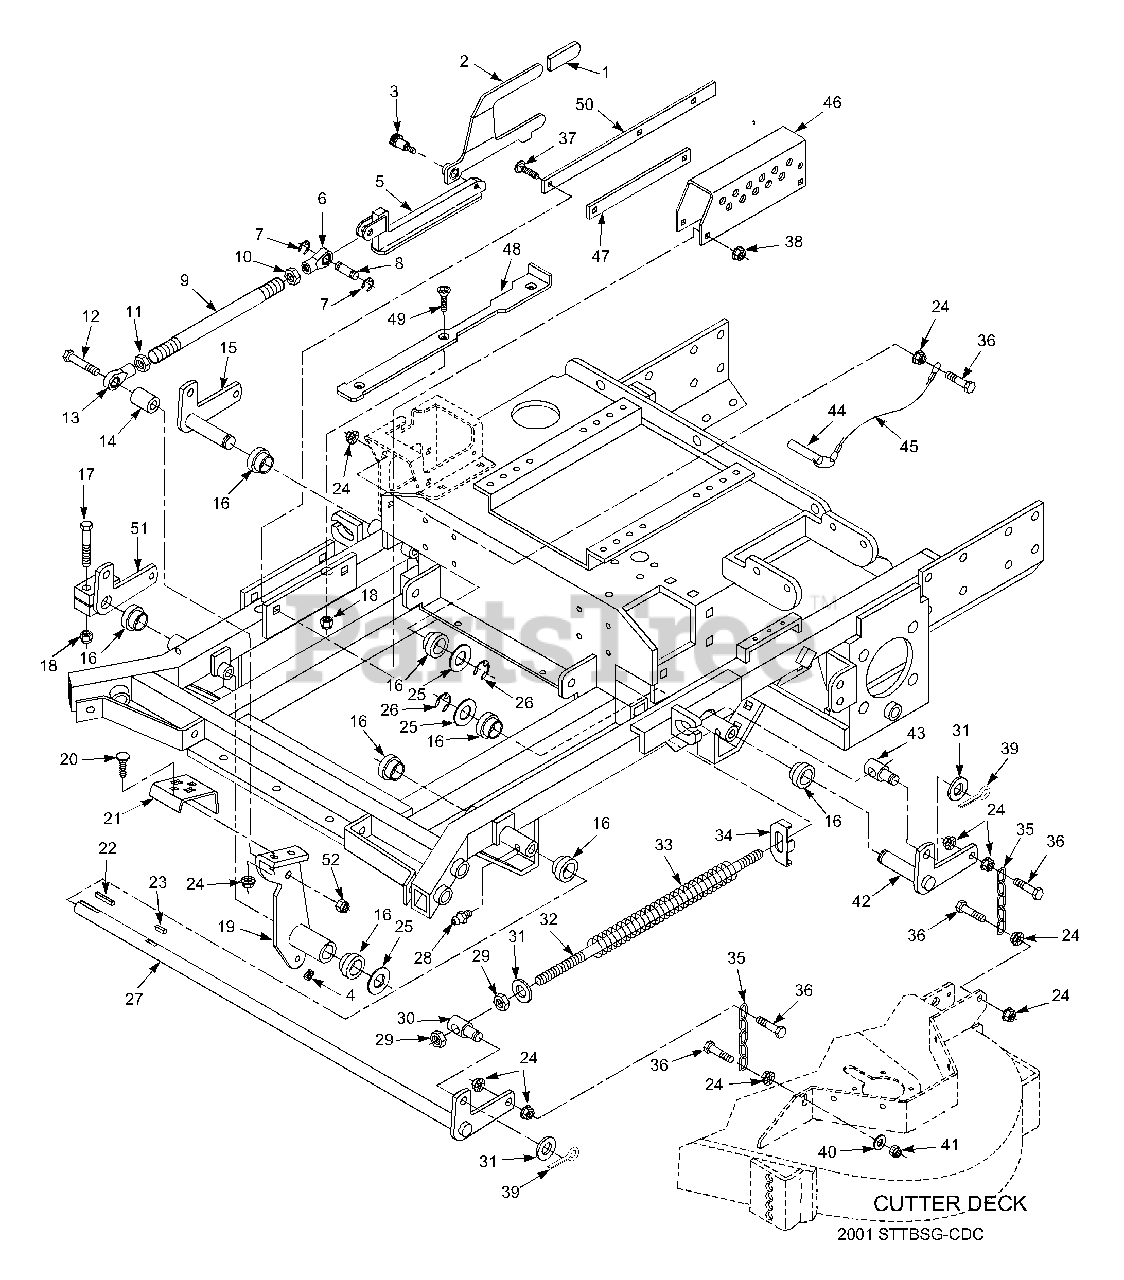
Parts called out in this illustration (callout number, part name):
1	Grip, Deck Latch
2	Deck Latch
3	Bolt, Shoulder 1/2 x 3/4"
4	Set Screw, 5/16-18 x 1/2" Sq. Head
5	Lockplate, Decklift
6	Rod End, Female - 1/2-20 LH
7	Ring, Retaining 1/2" External "E"
8	Pin, Decklift
9	Link, Decklift
10	Nut, Jam 1/2-20 LH
11	Nut, Jam 1/2-20 RH
12	Bolt, Hex Head 1/2-13 x 3"
13	Rod End, Female - 1/2-20 RH
14	Spacer, Decklift Pedal
15	Bellcrank Weldment, RH Rear
16	Bushing, 1.003 ID.
17	Bolt, Hex Head 7/16-14 x 2-1/2"
18	Nut, Hex Elastic Stop 7/16-14
19	Footplate Weldment, Decklift
20	Bolt, Carriage 5/16-18 x 1"
21	Footplate, Height Adjustment
22	Key, 1/4 x 1/4 x 1-1/4"
23	Key, 1/4 x 1/4 x 3-1/4"
24	Nut, 3/8-16 Hex, Serrated Flange
25	Flatwasher, 1" (1.062 x 1.50 x .048)
26	Ring, Retaining 1" External "E"
27	Bellcrank Weldment, LH Front
28	Grease Fitting
29	Nut, Hex 5/8-11
30	Swivel Joint, RH
31	Flatwasher, 5/8" (.656 x 1.312 x .095)
32	Stud, 5/8-11 x 22.0"
33	Spring, Deck Lift
34	Flatwasher, Spring Stop
35	Chain
36	Bolt, Hex Head 3/8-16 x 1-1/2"
37	Flatwasher, 5/8" (.656 x 1.312 x .095)
38	Nut, Hex 5/8-11
39	Pin, Cotter 3/16 x 1.0"
40	Flatwasher, 3/8"
41	Nut, 3/8-16 Elastic Stop
42	Bellcrank Weldment, LH Rear
43	Swivel Joint, LH
44	Ring Pin, 1/2 x 3.30"
45	Lanyard, Deck Height Pin
46	Bracket, Cutting Height Adjustment
47	Guide, Short
48	Lockplate, Decklift
49	Screw, Cap 5/16-18 x 3" FHHS
50	Guide, Long
51	Bellcrank Weldment, RH Front
52	Lock Nut, Hex Head 3/8-16
